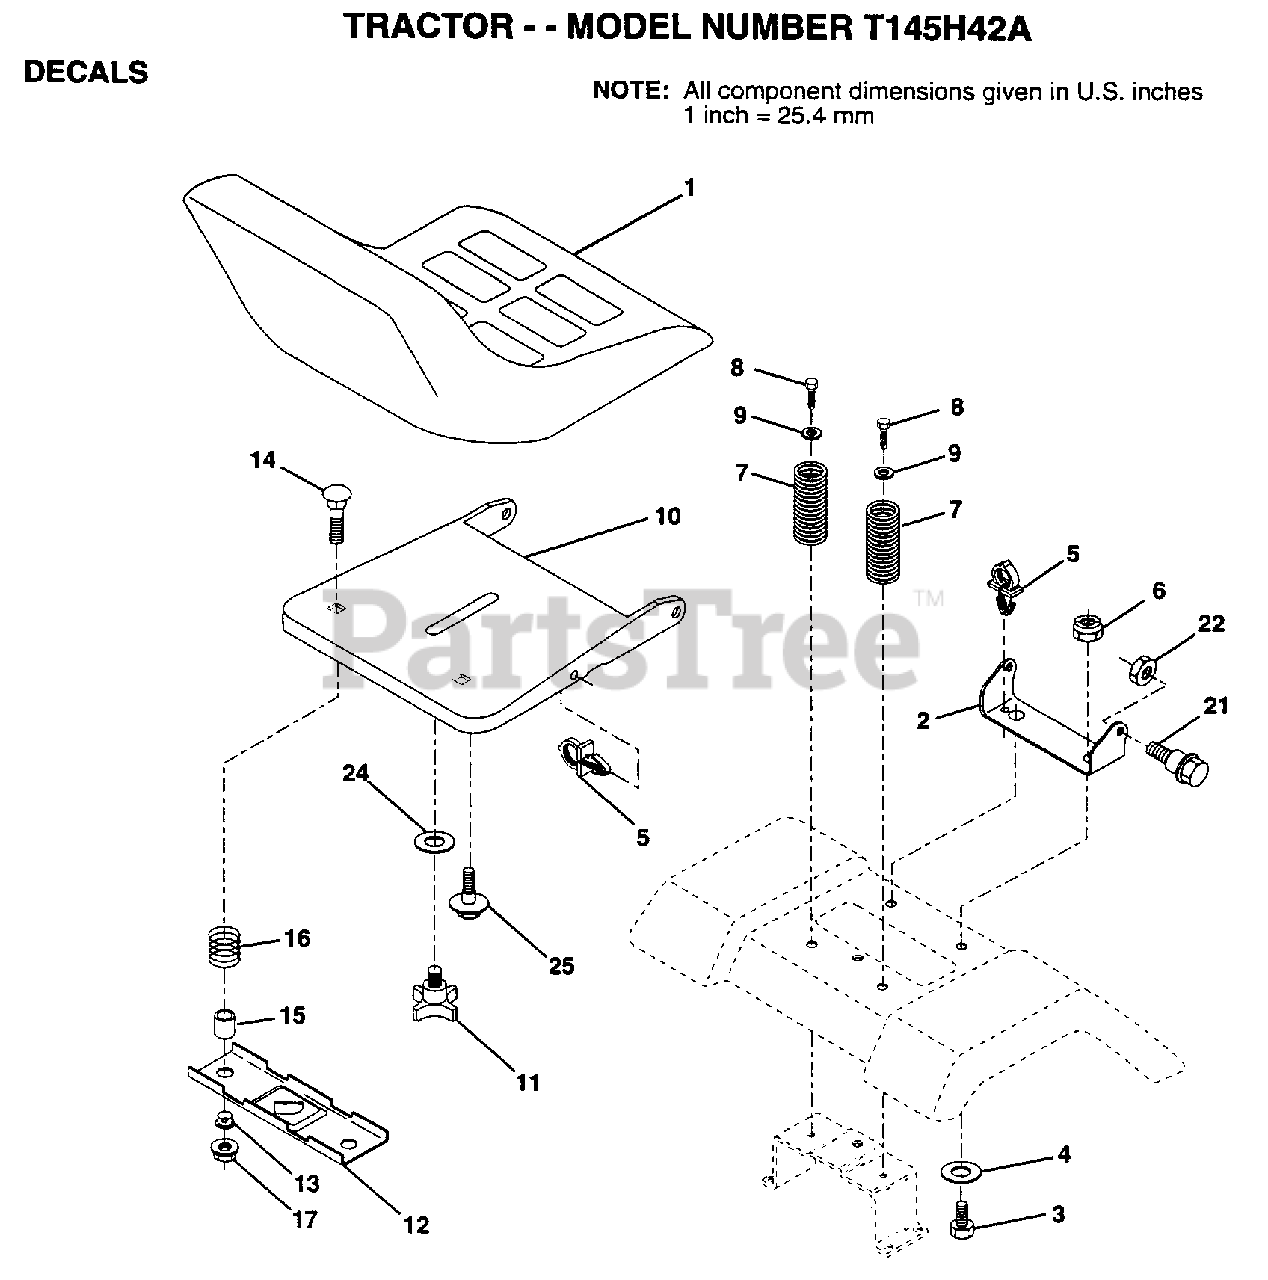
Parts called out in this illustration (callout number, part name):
2	BRACKET PVT SEAT
3	BOLT
4	WASHER PM
5	CLIP.PUSH-IN.HING
6	NUT
7	SPRING COMPRESSIO
8	SCREW GTV
9	WASHER
11	"KNOB 1/2"" YT"
12	BRKT SWITCH
13	BUSHING
15	SPACER SPLIT
16	SPRING COMPRESSED
21	BOLT.SHLD.5/16-18
24	WASHER
25	"BOLT,SHOULDER"
